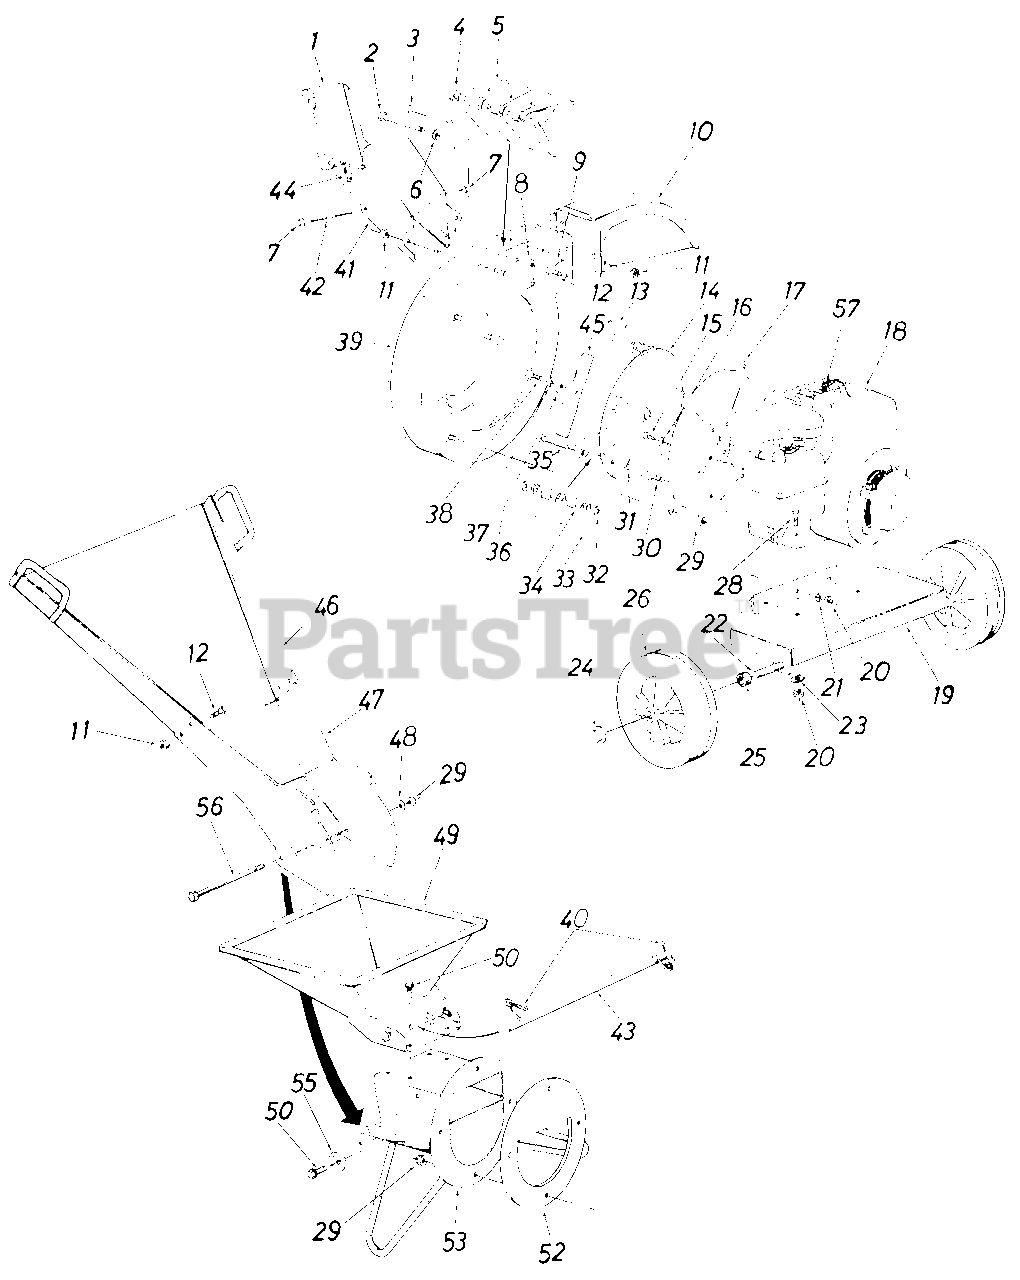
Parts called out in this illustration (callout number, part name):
1	Door Chip It
2	Hex Bolt 1/2-20 x 4.50" Lg.*
3	Clevis Pin
4	Flail Spacer 7/32" Lg.
5	Cutting Finger
6	L-Wash. 1/2" I.D.*
7	Palnut 3/16" Dia.
8	Hex Jam Nut 1/2-20 Thd.*
9	Cotter Pin 3/32" Dia. x 314" Lg.
10	Chute Deflector
11	L.-Nut 1/4-20 Thd.
12	Hex Bolt 1/4-20 x .50" Lg.*
13	Sq. Key 1/4" x 2.00" Lg.
14	Impeller Assembly
15	Hex Bolt 5/16-24 x 3/4" Lg.
16	L.-Wash. 5/16" I.D.*
17	Hopper to Engine Mtg. Plate
18	Engine
19	Engine Mounting Plate
20	Hex Nut 5/16-24 Thd.*
21	L.-Wash. 5/16" I.D.*
22	Shaft
23	Special L.-Wash. 5116" I.D.
24	Push Cap
25	Spacer
26	Wheel Ass'y.-Comp. (White)
26	Wheel Ass'y.-Comp. (Silver)
28	Hex Bolt 5/16-24 x 1.50" Lg.*
29	Elastic Lock Nut 5/16-18 Thd.
30	Hex Bolt 5/16-24 x .62" Lg.*
31	Cotter Pin 1/8" Dia. x 1.00" Lg.
32	Fl.-Wash. .531" I.D. x 937 0 O.D. x .09
33	Flail
34	Flail Spacer 23/32" Lg.
35	Clevis Pin .50" Dia. x 3.0" Lg.
36	Fl.-Wash. .406" I.D. x 1.25" O.D. Hdn.
37	L.-Wash. 3/8" I.D. H.D.
38	Hex Bolt 3/8-24 x 2.0" Lg. H.T.
41	Chip-lt Guide Ass'y.
42	Hinge Pin
43	Release Bar
44	Wing Nut Elastic 1/4-20 Thd.
46	Upper Leaf Ramp Section
47	Lower Leaf Ramp Section
48	Fl.-Wash. 5/16" I.D.
49	Hopper Assembly
50	Hex Wash. Hd. Self-Tap Scr. 5/16-18 x .75" Lg.
52	Back-Up Plate
53	Inlet Guide Assembly
55	Stop Washer
56	Hex Bolt 5/16-18 x 8.38" Lg.
57	Spark Plug Boot
